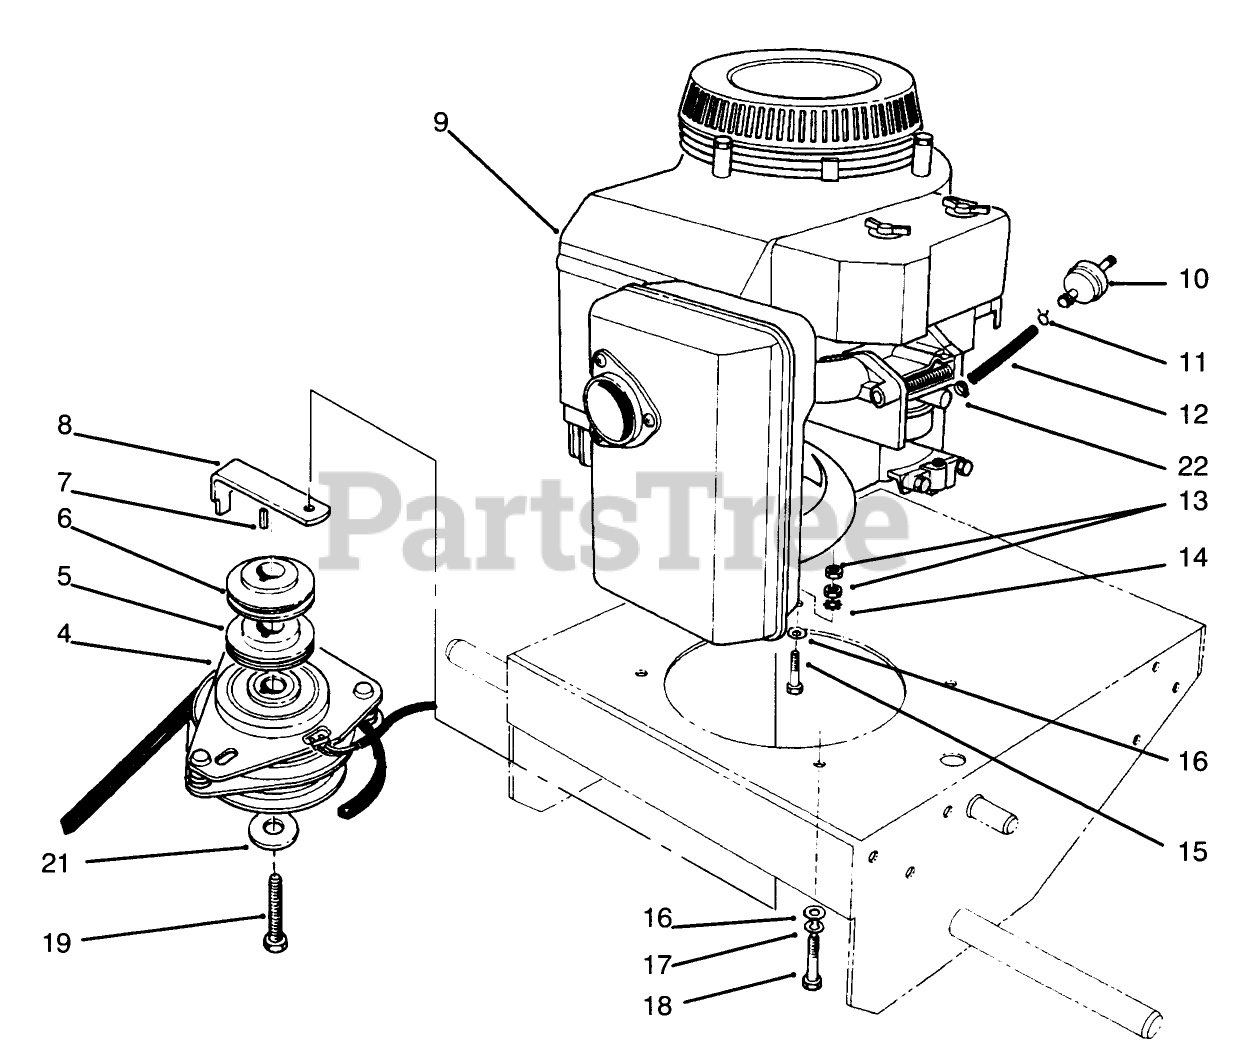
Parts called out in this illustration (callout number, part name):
4	CLUTCH/BRAKE
5	SHEAVE-LOWER HALF
6	SHEAVE-UPPER HALF
8	Retainer-Clutch
10	FILTER-FUEL
11	CLAMP-HOSE
12	HOSE-FUEL
13	NUT-JAM
14	WASHER-LOCK
15	SCREW (ENGINE, GROUND)
16	WASHER-PLAIN
17	WASHER-LOCK
18	SCREW-HH
19	SCREW-CLUTCH
21	WASHER
22	CLAMP-WORM
